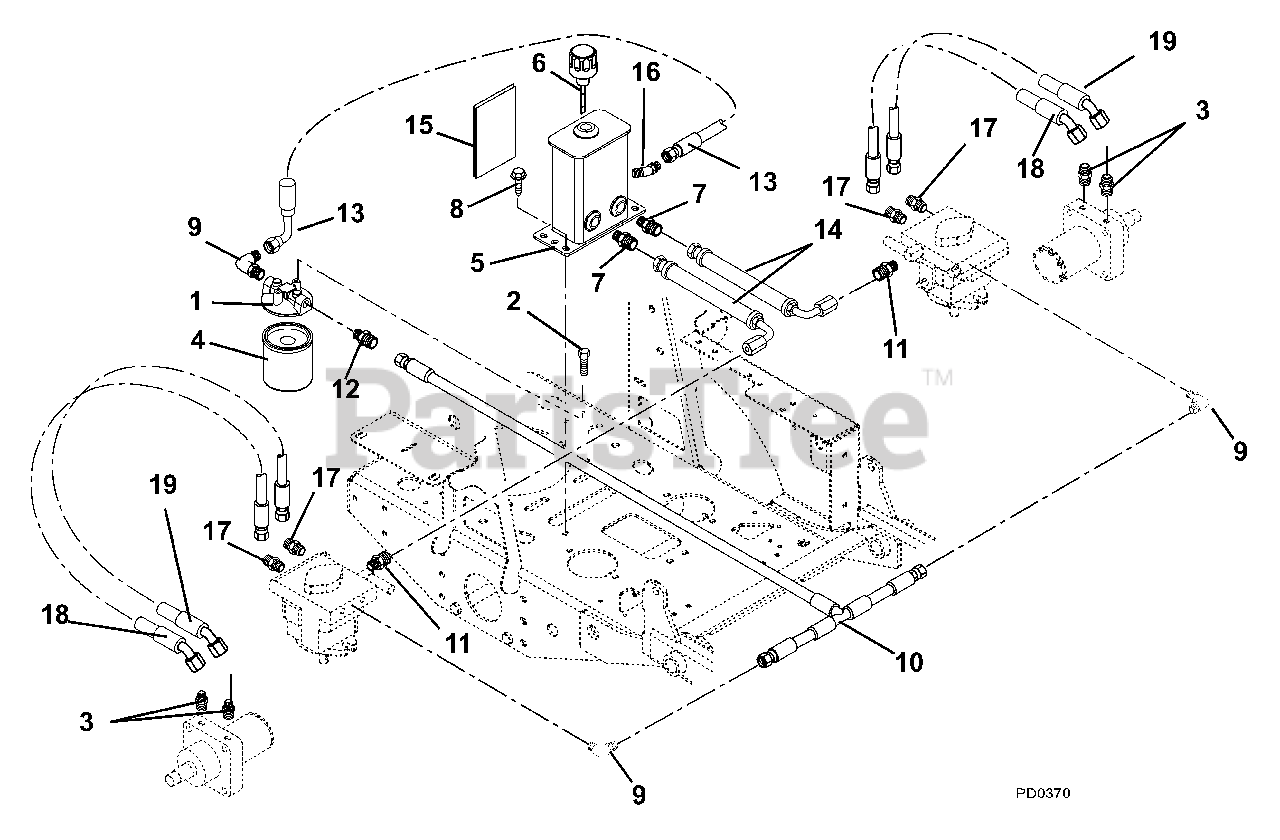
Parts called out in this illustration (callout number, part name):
1	Head, Filter
2	Bolt, Hex .25-20 x .50 Grade 5
3	Adapter, Hydraulic
4	Oil Filter
5	Tank, Hydraulic
6	Breather Dipstick
7	Fitting, Hydraulic Straight M8O-M4F
8	Screw, Tapping .38-16 x .50 Hex Washer Head
9	Fitting, Hydraulic
10	Hose, Hydraulic
11	Fitting, Hydraulic
12	Fitting, Hydraulic
13	Hose, Hydraulic
14	Hose, Hydraulic
15	Shield, Heat 5.50 x 4.50
16	Fitting, Hydraulic 45 Degree
17	Fitting, Hydraulic
18	Hose, Hydraulic .50-11-3K
19	Hose, Hydraulic .50-12-3K
